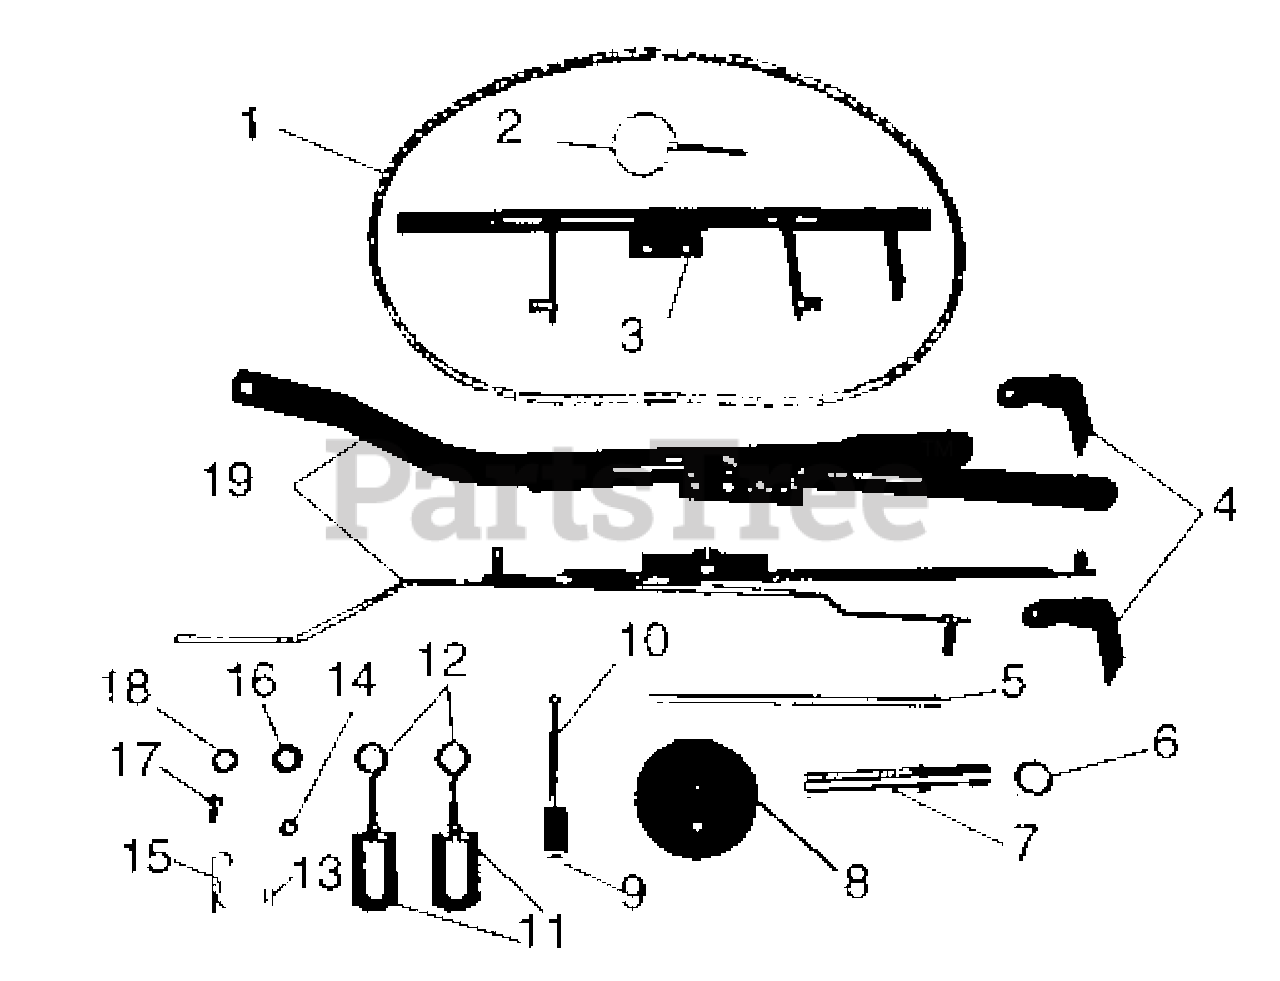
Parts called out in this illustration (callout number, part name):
1	V-BELT, HA-WRAPPED
2	PIN-KLIK .25X1.75
3	LIFT, WLDM'T
4	REAR HANGER
6	SPACER 1.004X1.500X.740
7	SHAFT - JACK
8	SHEAVE, JACKSHAFT 4.50
9	SPACER, IDLER - 48"
10	@BLT-HEX .38-16X4.50 GR5 YWZC
11	WELDMENT, ADJUSTMENT LINK
12	BLT-EYE .375-16X2.50 YWZC
13	CLIP, SPRING
14	@NUT-LK-TOP-FLG .38-16 YWZC
15	PIN-HAIR-EXT .12X.31X2.37 YWZC
16	WSHR-FL-STL .531X1.250X.10 YWZ
17	BLT-SERHFWH .38-16X.75 YWZC
18	@WSHR-FL-STL.531X1.06X.095YWZC
19	Lift Link Assembly
